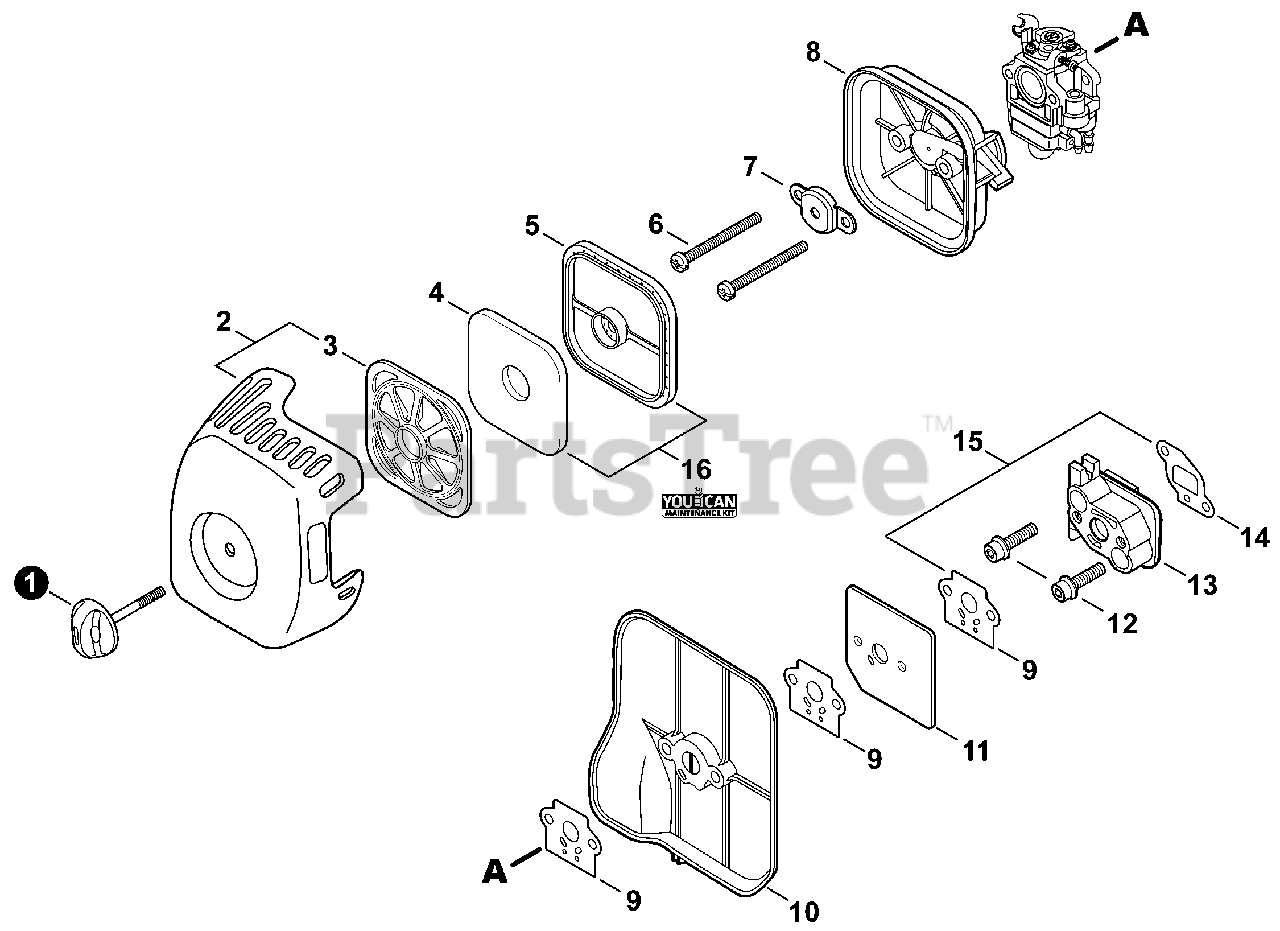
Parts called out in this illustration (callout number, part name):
1	THUMBSCREW
2	COVER KIT, AIR FILTER
3	RETAINER, PRE-FILTER
4	PRE-FILTER, FOAM
5	FILTER, AIR - DOUBLE LAYER
6	SCREW 5×70
7	PLATE, PREVENT
8	CASE, AIR FILTER
9	GASKET, INTAKE
10	PLATE, INSULATOR
11	PLATE, INSULATOR
12	BOLT 5×30
13	INSULATOR, INTAKE
14	GASKET, INTAKE
15	GASKET KIT
16	TUNE-UP KIT - YOUCANT
